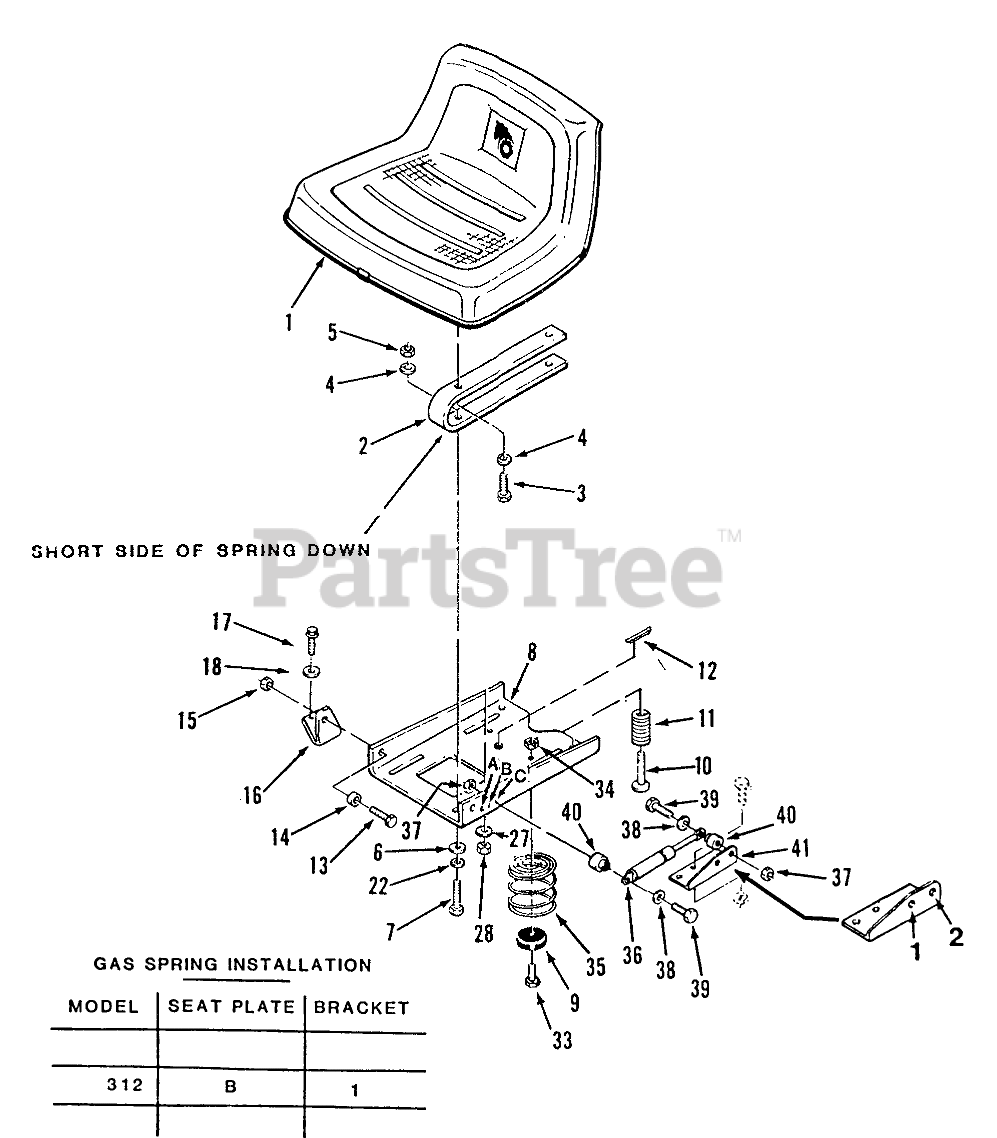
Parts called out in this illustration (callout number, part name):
1	Seat 312, 414
2	Seat Spring
3	Bolt
4	Lockwasher
5	Nut
6	WASHER 5/16 SAE
7	HHCS
8	PLATE-SEAT PIVOT B
9	BUMPER
11	SPRING-SEAT SWITCH
12	Cotter Pin
13	HHCS
14	BUSHING
15	Nut
16	Bracket-Pivot RH
17	Bolt
18	WASHER 5/16 SAE
30	RIVET
31	SPRING SWITCH
33	Bolt
34	Nut
35	SPRING
36	GAS SPRING
37	Nut
39	Bolt
40	SPACER
41	BRKT-DAMPER B
